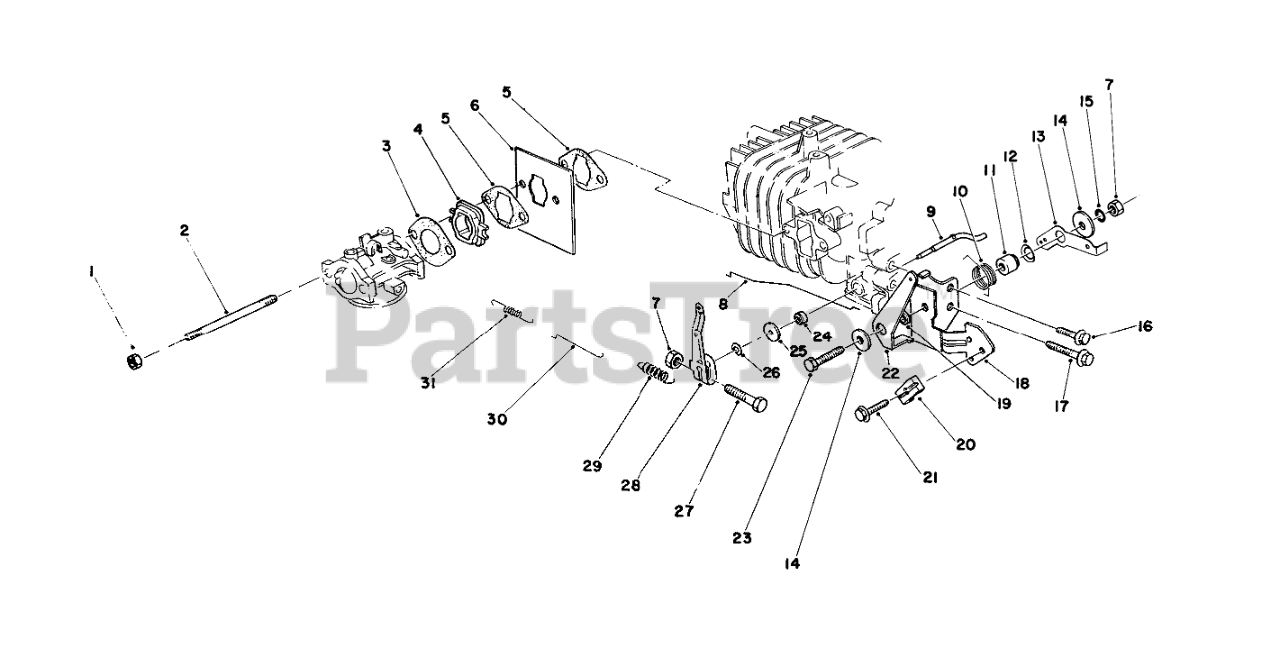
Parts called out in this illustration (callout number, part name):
1	NUT-LOCK
2	CARB STUD BOLT
3	GASKET-CARB
4	INSULATOR
5	GASKET
6	SHIELD
8	CHOKE ROD
9	Shaft-Govemor
10	Spring-Choke Control Lever
11	Gov Lever Spacer
12	Washer-Gov. Spring Lever
13	GOV SPRING LEVER
14	WASHER
15	LOCKWASHER
18	Bracket-Throttle Control
19	Spacer-Choke Control Lever
20	CLAMP-CABLE
22	LEVER-CONTROL, CHOKE
24	SEAL-OIL
25	WASHER
26	E-RING
28	Lever-Throttle Control
29	GOVERNOR SPRING
30	ROD-CARBURETOR
31	SPRING
